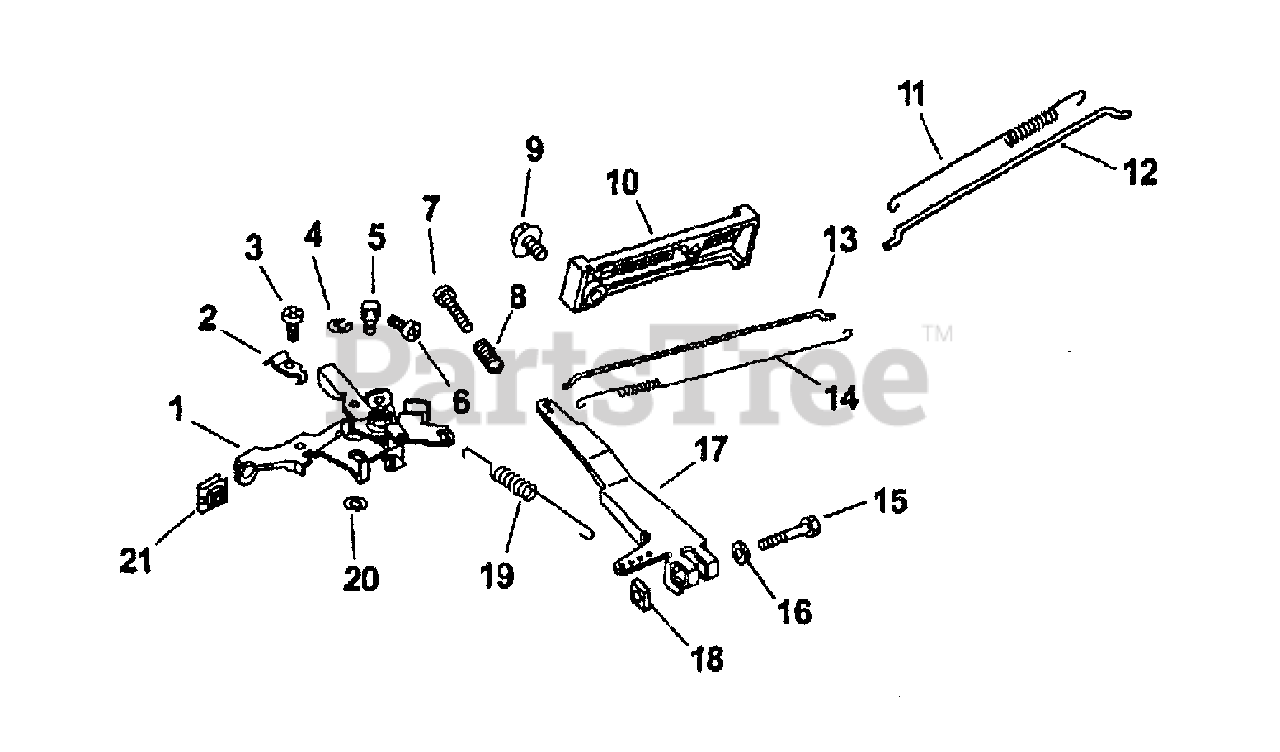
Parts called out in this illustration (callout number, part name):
1	Assembly, Throttle
2	Clamp, Bowden
7	Screw, Pan Head
8	Spring, Compression
10	Panel, Speed & Choke
11	Spring, Choke
13	Link, Throttle
14	Spring, Linkage
17	Lever, Governor
19	Spring, Governor
